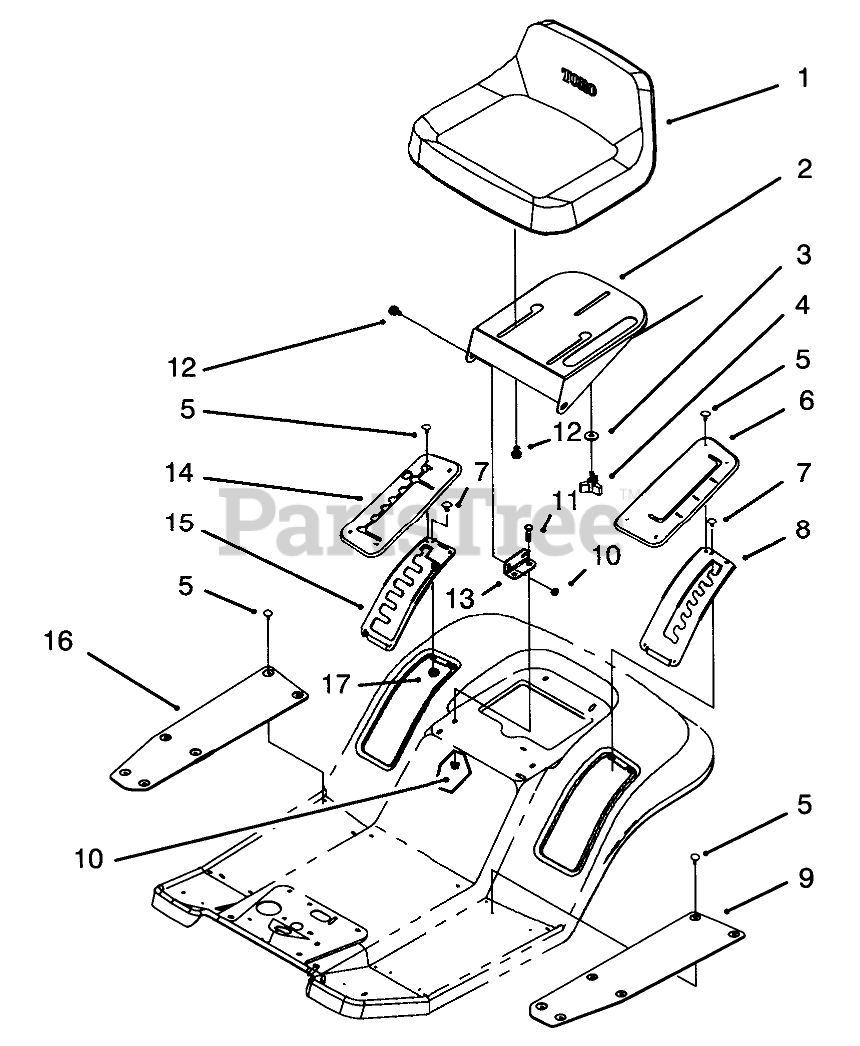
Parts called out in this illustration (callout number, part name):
2	Support-Seat
3	WASHER-PIVOT
5	FASTENER-PANEL
6	COVER-HOC
7	RIVET-POP
8	Gate-H.O.C.
9	MAT-FOOT, LH
10	NUT-LOCK, NI
11	SCREW-HH
12	BOLT-SHOULDER
13	Bracket-Seat Hinge
14	COVER-GATE, SHIFT
15	Gate-Shift
16	MAT-FOOT, RH
17	WASHER-FLAT
